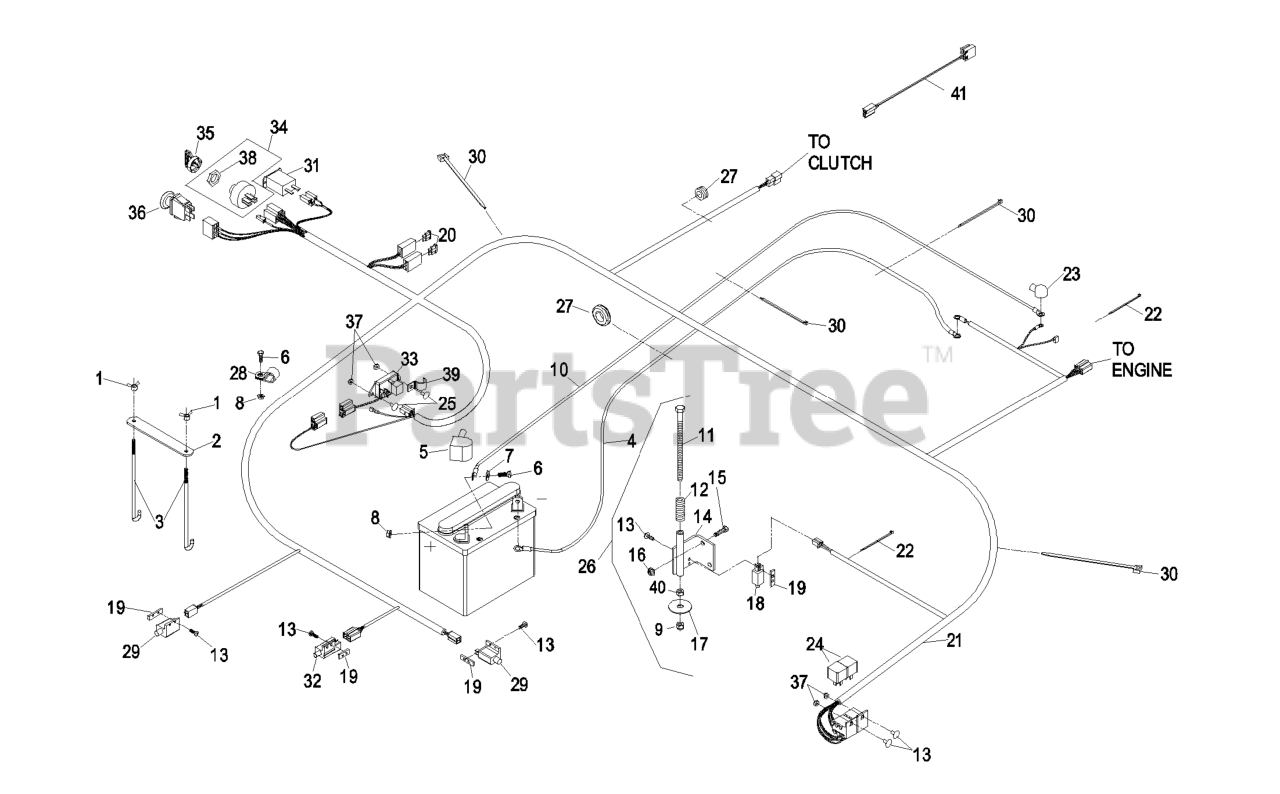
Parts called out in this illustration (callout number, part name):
1	WINGNUT
2	STRAP-HOLDDOWN, BATTERY
3	BOLT-HOLDDOWN
4	CABLE-GROUND, NEGATIVE
5	INSULATOR-BATTERY
6	SCREW-HH
7	WASHER-FLAT
9	NUT-LOCK, NI
10	POSITIVE BATTERY CABLE AS
11	SCREW-HH
12	SPRING-SWITCH, SEAT
13	SCREW-PPH
14	BRACKET-SWITCH, SEAT
15	SCREW-HH
18	SWITCH-CLOSED, NORMALLY
19	PLATE-TAPPED
20	FUSE-BLADE TYPE, 20 AMP
21	HARNESS,WIRE LHP KC
22	TIE-CABLE
23	INSULATOR-SOLENOID
25	SCREW-HEAD, TRUSS
26	ASM,SEAT SWITCH ACTUATOR
27	GROMMET
28	CLIP-LOOM
29	SWITCH-OPEN, NORMALLY
30	TIE-PLASTIC
31	METER-HOUR
33	MODULE-DELAY, SEAT
34	ASM,SWITCH W/NUT
35	KEY-IGNITION
36	SWITCH-PTO
37	NUT-LOCK, NI
38	NUT-SWITCH, IGNITION
39	CLIP-HALF, LOOM
40	NUT-HEX
41	HARNESS-CLUTCH
